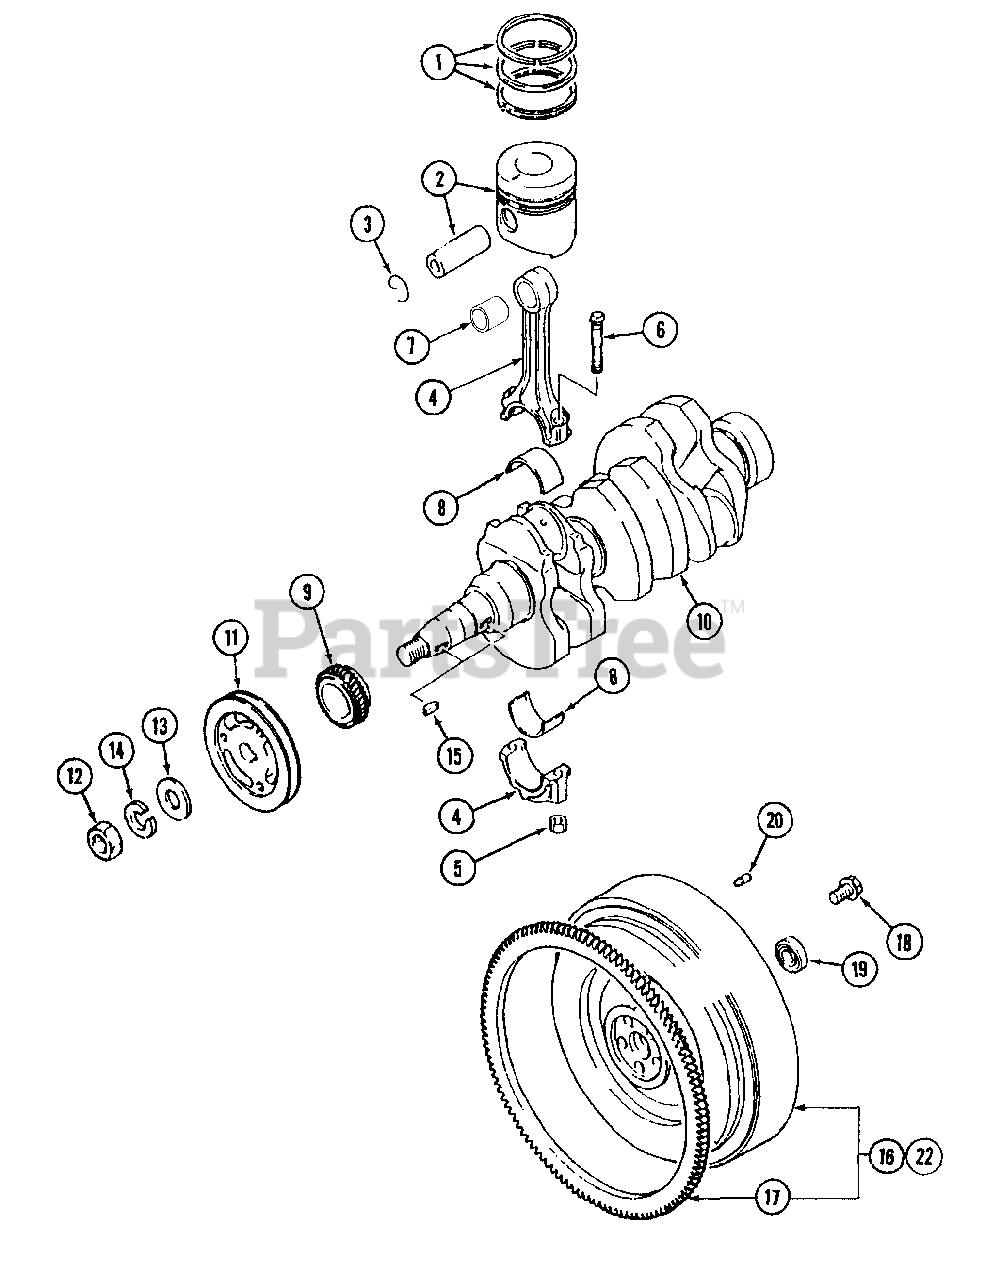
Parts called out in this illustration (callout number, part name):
1	Ring Set, Piston
2	Piston & Pin Set
3	Clip, Piston Pin
4	Rod Ass'y., Connecting
4	Connecting Rod & Cap
5	Nut, Connecting Rod
6	Bolt, Connection Rod
7	Bearing, Small End
8	Bearing Set, Con. Rod
9	Gear, Crankshaft
10	Crankshaft
11	Pulley, Crankshaft
13	Washer, Plain
14	Washer, Spring
15	Key, Woodruff
16	Flywheel Ass'y
18	Bolt, Drive Plate
19	Bearing, Ball
20	Pin, Dowel
22	Flywheel Ass'y.
